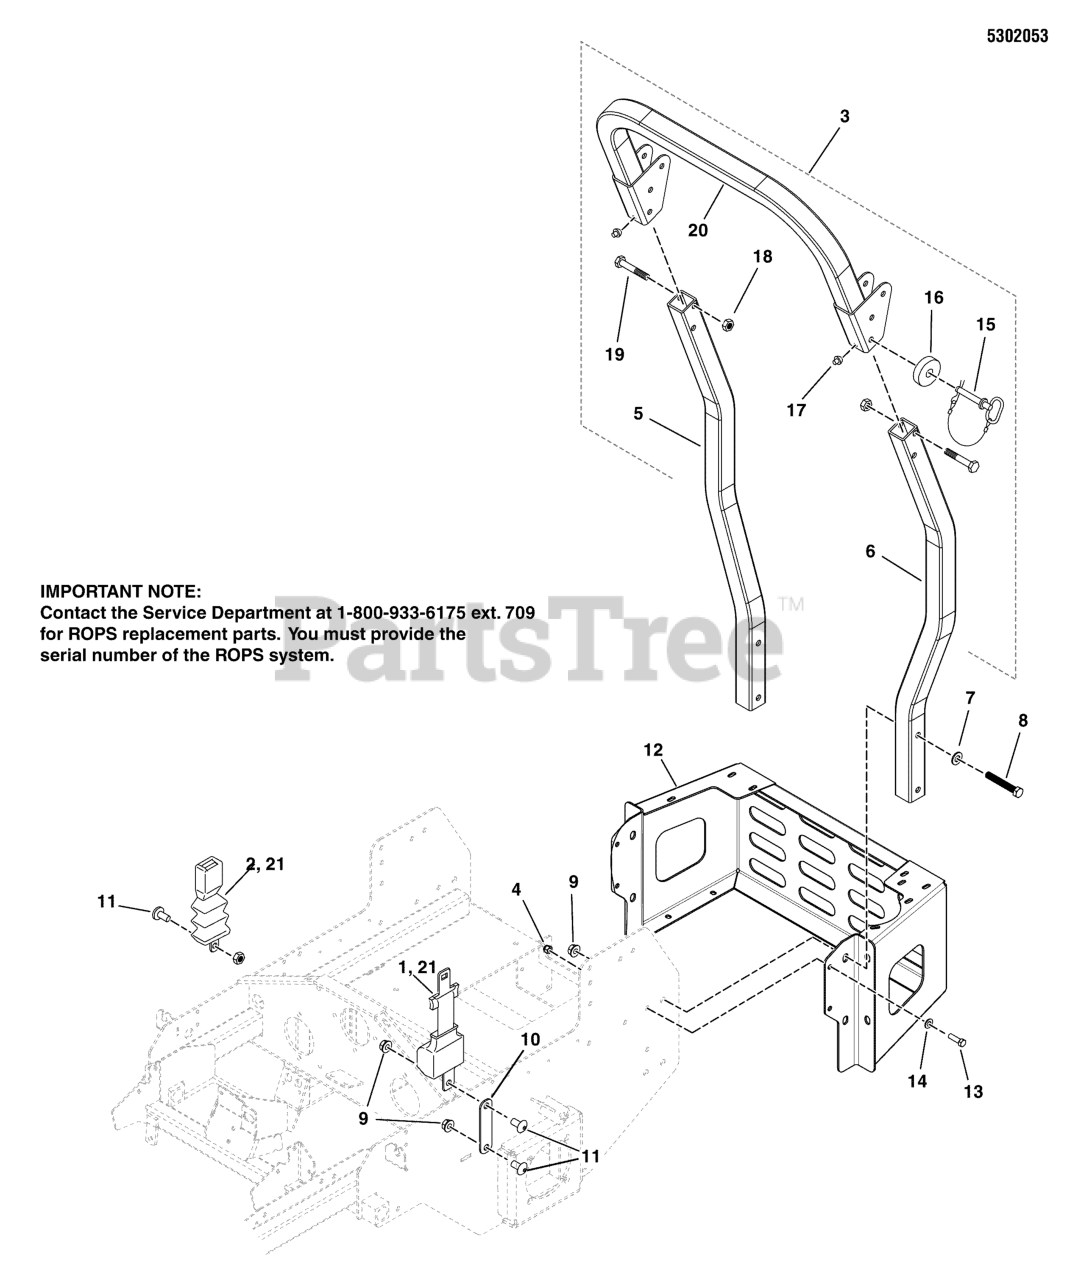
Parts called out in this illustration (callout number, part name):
1	ORDER P/N 5105137 (CONTAINS BOTH SEAT BELT RETRACTOR + SUPER SLEEVE BUCKLE)
2	SEAT BELT ASSM, RETRACTOR + SUP SLEEVE
3	ROPS (Call 1-800-933-6175 ext. 2193 if replacing a ROPS)
4	NUT, 3/8-16 HEX NYLON LOCK
5	ROLL BAR POST, RH
6	ROLL BAR POST, LH
7	WASHER, 1/2 SAE
8	BOLT, 1/2-13 X 3-1/4, HEX HD, GD5, CZ (SV)
9	NUT, Hex Flange, Nylock, 1/2-13
10	EXTENSION, SEAT BELT - BLK
11	SCREW, 1/2-13 X 1.00, SHCS
12	WELD, BUMPER, S175X - RED
13	BOLT, 3/8-16 X 1" GD5 CZ
14	WASHER, 3/8 SAE
15	PIN, HINGE W/ LANYARD
16	WASHER, EPDM FOAM, 1/2" ID
17	BUMPER, ROPS
18	NUT
19	BOLT
20	ROLL BAR TOP LOOP
21	SEAT BELT, RETRACTING - ASSM
